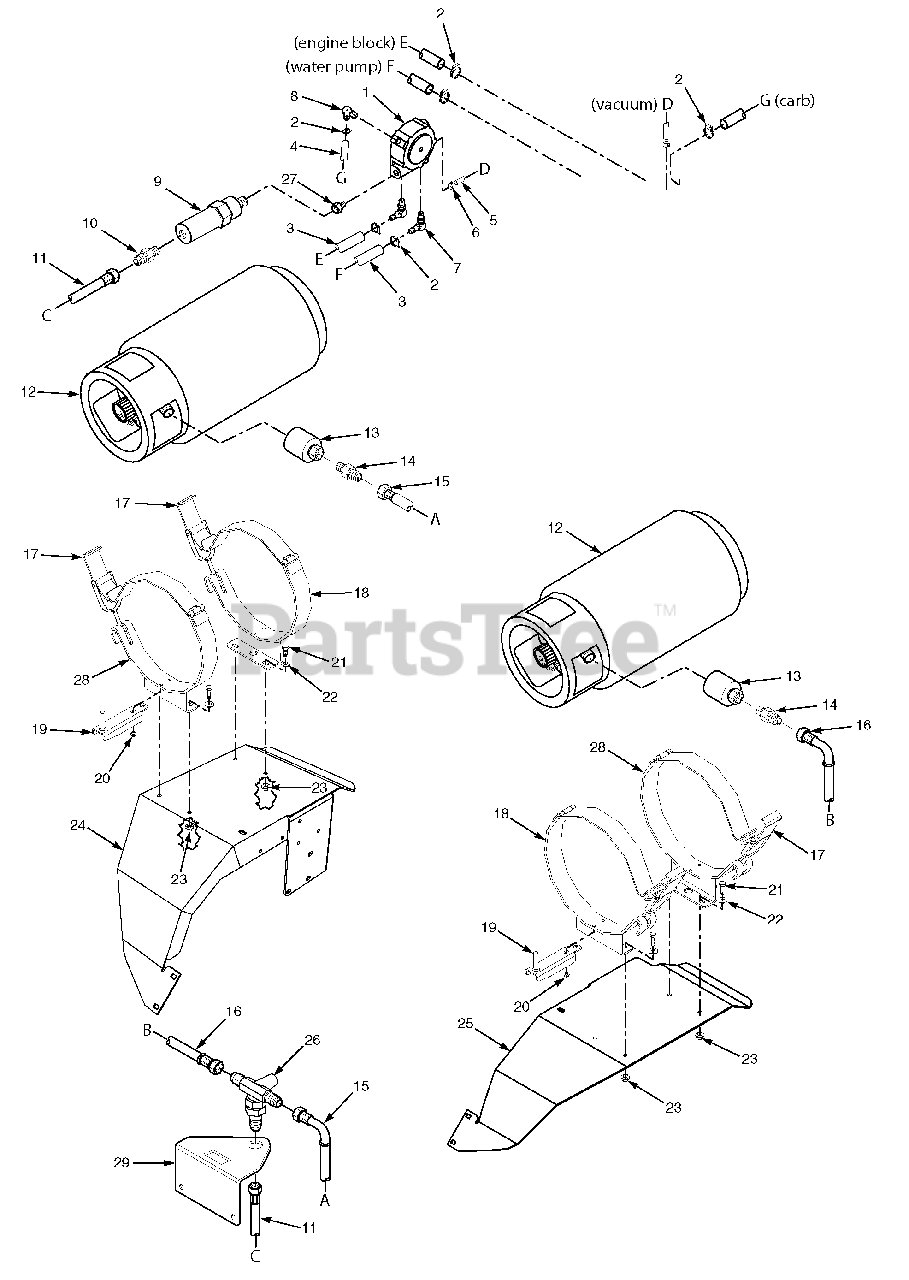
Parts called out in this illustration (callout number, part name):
1	Regulator, Kubota
2	Clamp, 0.87 Max. Dia.
3	Hose, 3/8" ID 300 PSI
4	Hose, LP
5	Hose, Vacuum Line
6	Clamp, 3/16" Hose ID
7	Fitting, 90 Degree - Kubota
8	Fitting, 90 Degree - Kubota
9	Lockoff Valve LP, Electric
10	Fitting, Union 3/8" Flare x 1/4" Pipe
11	LP Fuel Line, 45-1/2" (to Regulator)
12	LP Fuel Tank
13	LP Quick Coupler
14	Fitting, Union 3/8" Flare x 1/4" Pipe
15	LP Fuel Line, 26-1/2" (RH Tank)
16	LP Fuel Line, 52" (LH Tank)
17	LP Tank Lock Bracket
18	Front LP Tank Mounting Bracket
19	LP Tank Locating Bracket
20	Bolt,
21	Bolt, Hex Head 3/8-16 x 1"
22	Flatwasher, 3/8-.391 x .938 x .105
23	Nut, Serrated Flange 3/8-16
24	Fender Weldment, RH
25	Fender Weldment, LH
26	T-Connector, w/check valves
27	Fitting, Kubota
28	Rear LP Tank Mounting Bracket
29	Mounting Bracket, Tee Fitting and Selector Switch
